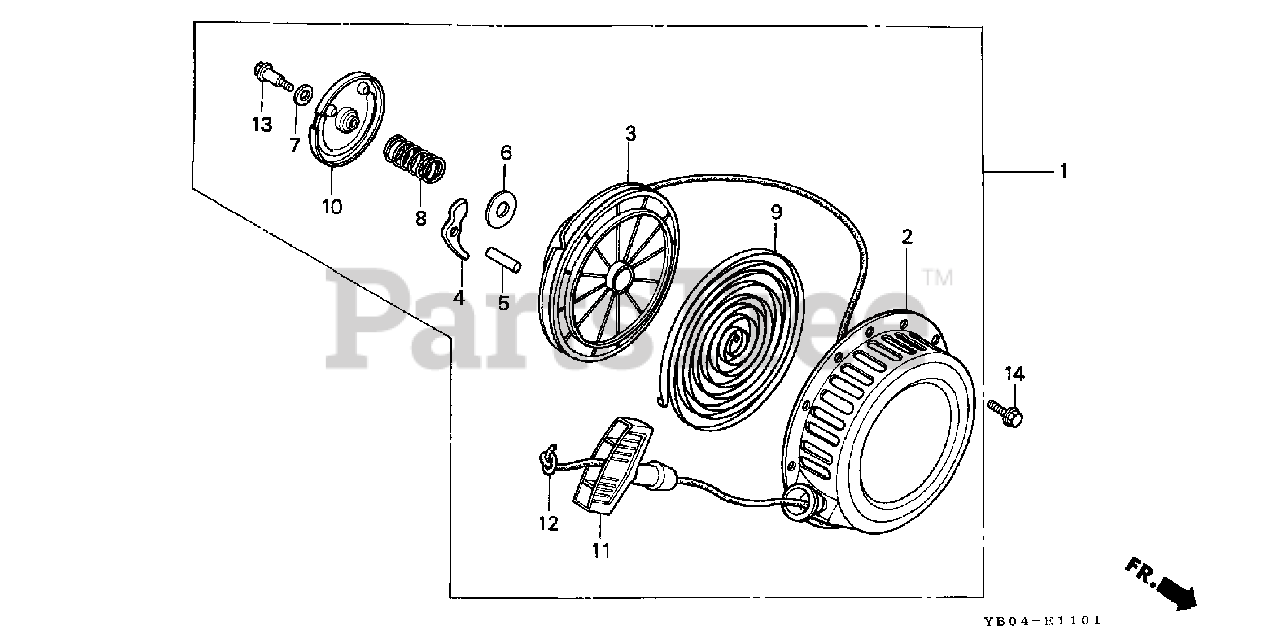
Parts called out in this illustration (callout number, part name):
1	STARTER, RECOIL
2	CASE, STARTER
3	REEL, STARTER
4	RATCHET, STARTER
5	SHAFT, RATCHET
6	PLATE A, FRICTION
7	PLATE B, FRICTION
8	SPRING, FRICTION
9	SPRING, RETURN
10	COVER, REEL STARTER
11	GRIP, STARTER
12	ROPE, STARTER (#4X65") (N/A: USE P/N 08540-ZG921-11)
13	BOLT, REEL COVER
14	BOLT, FLANGE (6X8)
